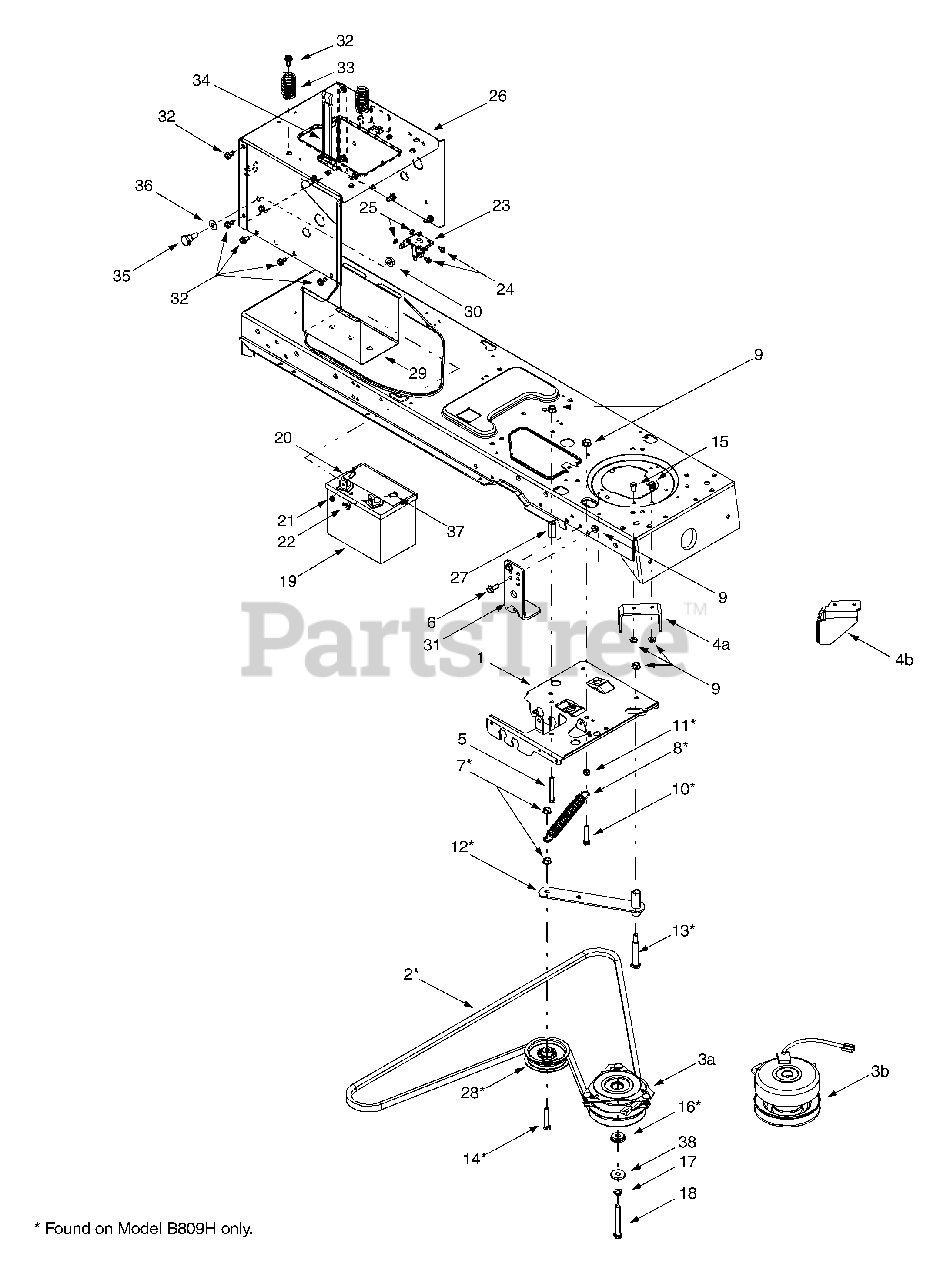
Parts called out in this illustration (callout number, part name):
2	PTO Belt
3A	Electric PTO Clutch (Model B809H)
3B	Electric PTO Clutch (Model R809K)
3B	Washer, Flat, 1.031 x 1.62 x .095
6	Hex Head Washer Screw, 5/16-18 x .875
7	Flange Lock Nut, 3/8-16
8	Extension Spring, .62 x 5.62
9	Flange Lock Nut, 5/16-18
10	Hex Cap Screw, 5/16-18 x 1.75
11	Hex Nut, 5/16-18
12	Idler Bracket Assembly
13	Shoulder Screw, 1/2 x 2.5
14	Hex Cap Screw, 3/8-16 x 2.0
15	Hex Cap Screw, 5/16-18 x .625
16	Shoulder Spacer, 1.38 x .445 x .36
17	Lock Washer, 7/16
18	Hex Cap Screw, 7/16-20 x 3.25 (Grade 5)
19	12-volt Battery, 270 CCA
20	Hex Cap Screw, 1/4-20 x .62
21	Hex Sems Nut, 1/4-20
22	Wing Nut, 1/4-20
23	Solenoid, 12-Volt, 100 Amp
24	Self Tapping Screw, 1/4-20 x .5
25	Lock Washer, 1/4
28	Idler Pulley, 3.5
32	Self Tapping Screw, 5/16-18 x .625
33	Compression Spring, 1.28 x 3.5
34	Battery Strap
35	Shoulder Screw, .625 x .5, 7/16-20
36	Bell Washer, .45 x 1.0 x .062
37	Shoulder Screw, 1/4-20, .25 x .15
38	Flat Washer, .45 x 1.25 x .164
